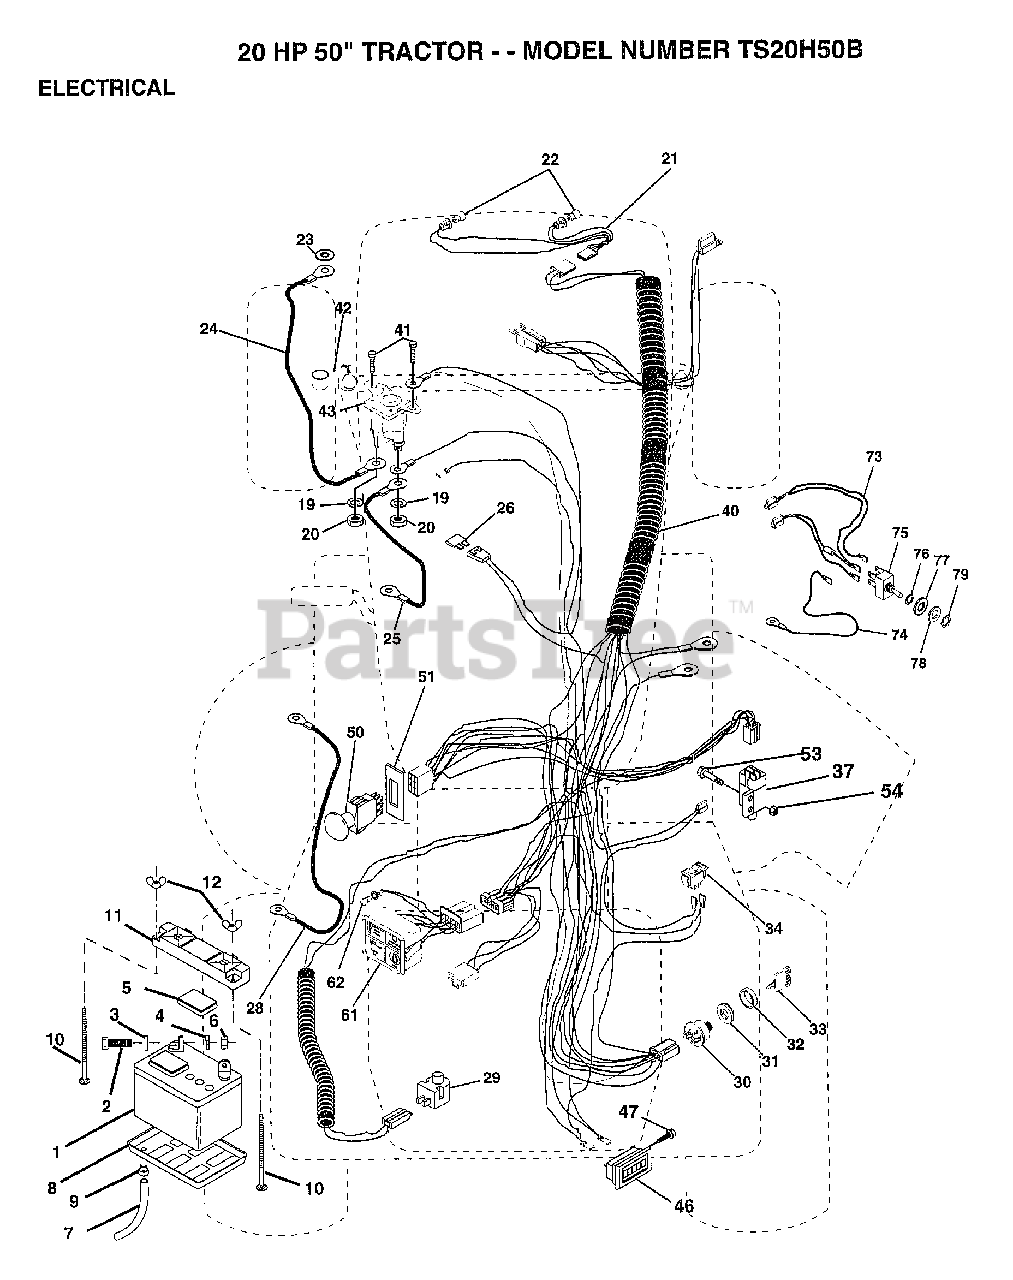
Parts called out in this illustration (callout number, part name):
2	BOLT LT
3	LOCKWASHER
4	WASHER
5	"CAP,BATTERY "
7	"DRAIN TU T, BATT"
8	"TRAY T, BATTERY"
9	HOSE CLAMP T
10	BOLT
20	NUT
22	HEADLAMP BULB
23	LOCKWASHER
24	"CABLE T, BATTERY"
25	CABLE-BATTERY T
26	FUSE HYT
28	CABLE T
29	SWITCH SEAT
32	COVER KEY SWITCH
33	KEY MLD GEN DELTA
34	SWITCH LT
37	SWITCH INTERLOCKT
40	HARNESS IGNITION
41	SCREW
46	HOUR METER T
47	SCREW
51	RING RETAIN PTO
53	SCREW
54	"NUT,KEPS"
61	LIGHT.PKG.ASM.
62	BULB LIGHT T
73	"HARNESS,WIRE"
74	WIRE LIFT SWI T
78	WASHER
